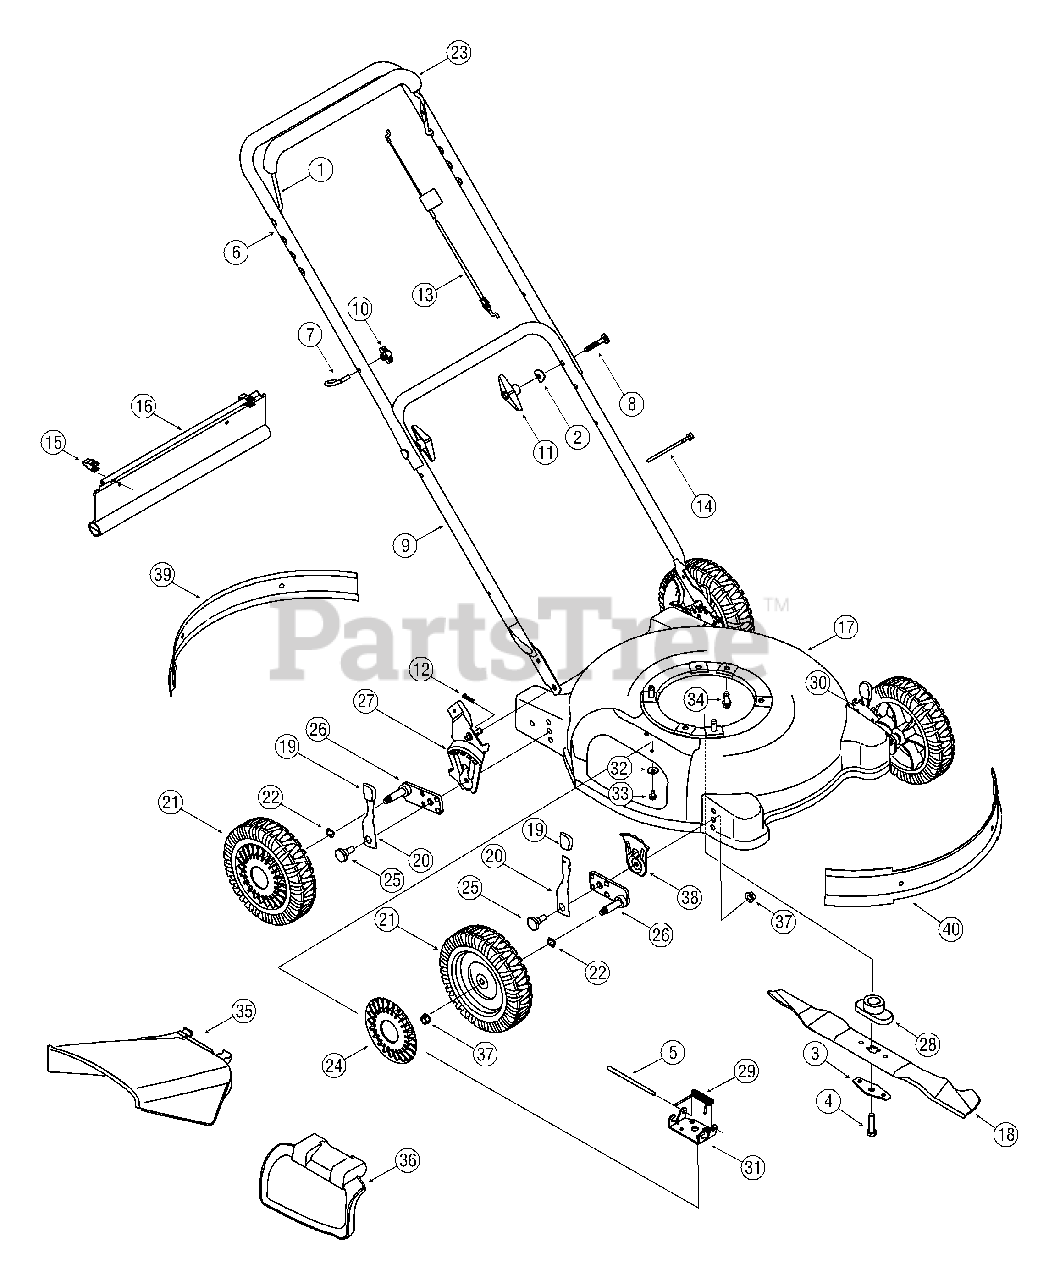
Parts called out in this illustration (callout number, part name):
2	Saddle Washer
3	Blade Bell Support
5	Hinge Pin
8	Carriage Bolt
12	Hairpin Clip
13	Control Cable 48.25"
14	Cable Tie
15	Hinge Clip
19	Height Adjustment Knob
20	Spring Lever
21	Wheel Assembly
22	Wave Washer
23	Snap-On Bail Cover
24	Hubcap: Radial Spoke Gray
25	Shoulder Bolt
26	Pivot Arm Assembly - RH
28	Blade Adapter
29	Torsion Spring
30	Height Adjust. Assembly LH
33	Hex Washer Hd. TT Screw
34	TT Sems Screw
35	Chute Deflector
36	Mulching Plug Assembly
37	Hex Lock Nut
38	Height Adjustment Plate
